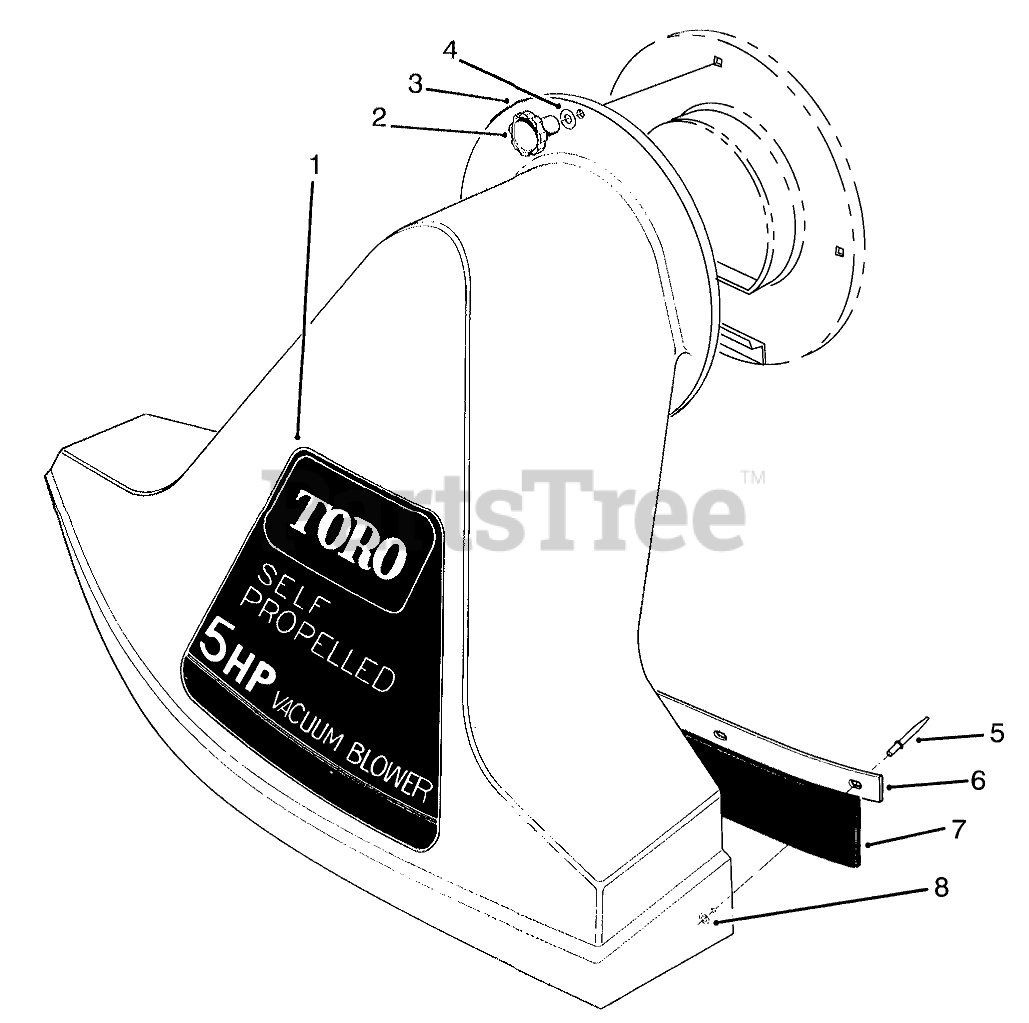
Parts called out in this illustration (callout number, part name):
1	DECAL-VACUUM SP
3	Snout Assembly (Incl. Ref. #5-8)
4	Washer
5	POP RIVET 3/16X.375LG
6	Clamp-Flap
7	FLAP-RUBBER
8	WASHER-FLAT
